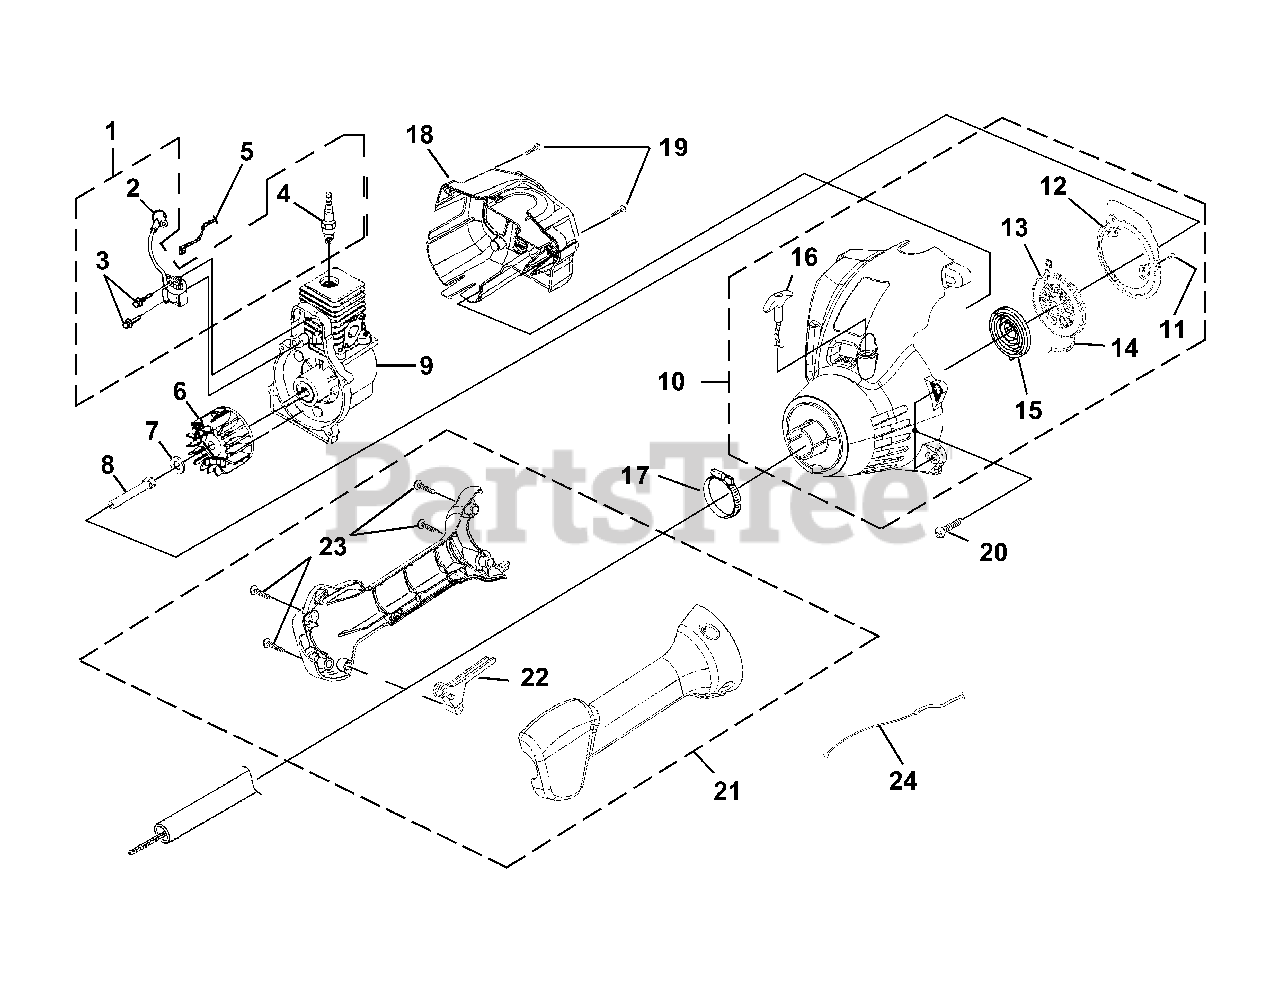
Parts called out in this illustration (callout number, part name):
1	IGNITION KIT
2	TERMINAL & COVER
3	SCREW-Taptite (8-32 X 1")
4	SPARK PLUG
5	LEAD-Electrical
6	ROTOR KIT
7	WASHER-Flat
8	CONNECTOR-Drive (.250)
9	SHORT BLOCK
10	COMPLETE STARTER ASSEMBLY
11	SCREW-Thread Form (8-16 X 1/2")
12	BAFFLE-Air
13	PULLEY-Starter
14	ROPE-Starter (42")
15	SPRING & CONTAINER
16	GRIP-Starter (Yellow)
17	CLAMP
18	HOUSING-Rear Kit
19	SCREW-Truss (10-14 X 7/8")
20	SCREW-Taptite (10-24 X 3/4")
21	CONTROL HANDLE ASSY.
22	TRIGGER
23	SCREW-Truss Hd. (10-14 x 7/8")
24	CABLE-Throttle
